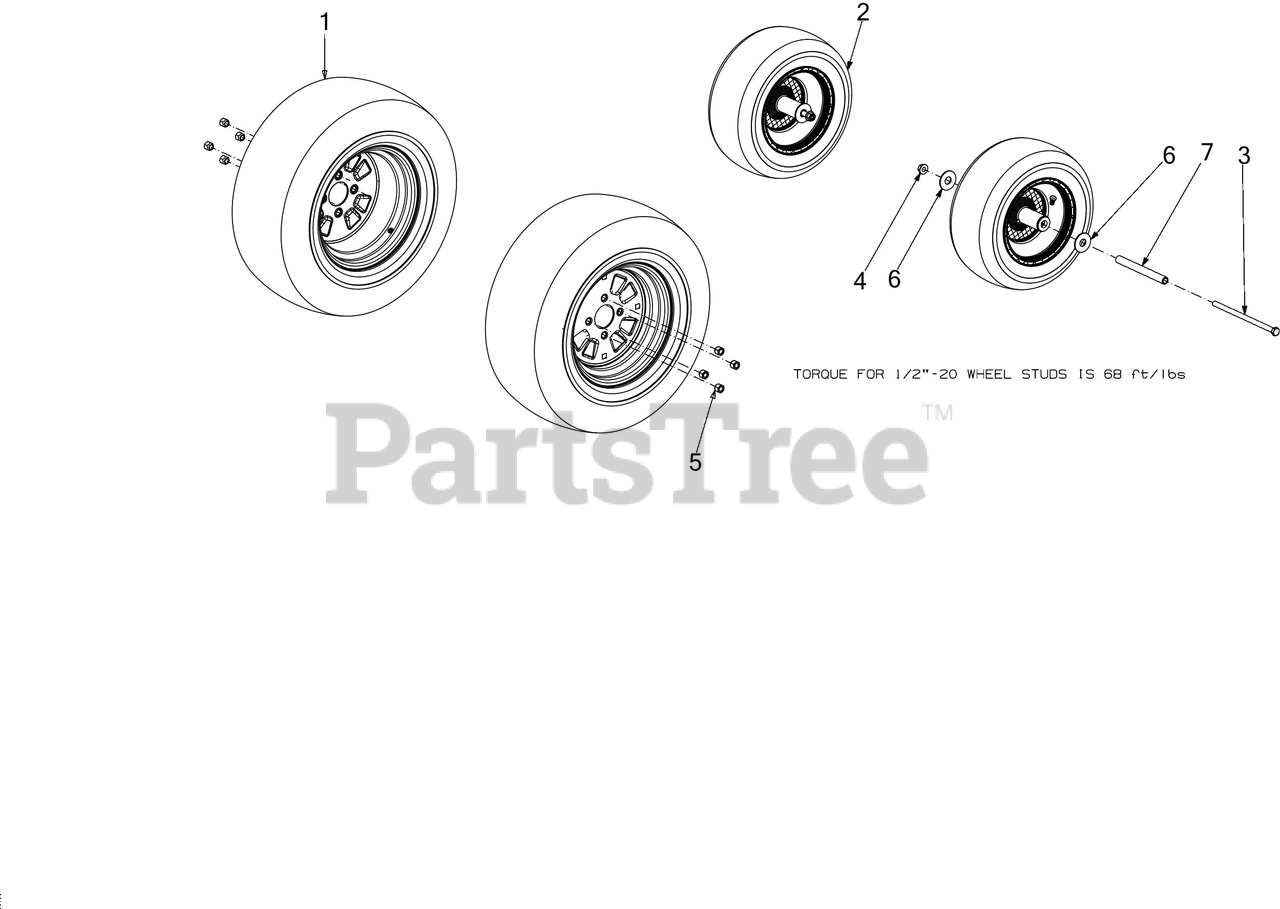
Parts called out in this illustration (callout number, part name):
1	WHEEL ASSEMBLY (24 x 9.5 x 12)
2	WHEEL ASSEMBLY (15 x 6.5-8)
3	SCREW 1/2-13 x 9.5 GR5
6	FLAT WASHER .75ID x 2.00D x .10
7	SPACER 51IDX750DX7.38
